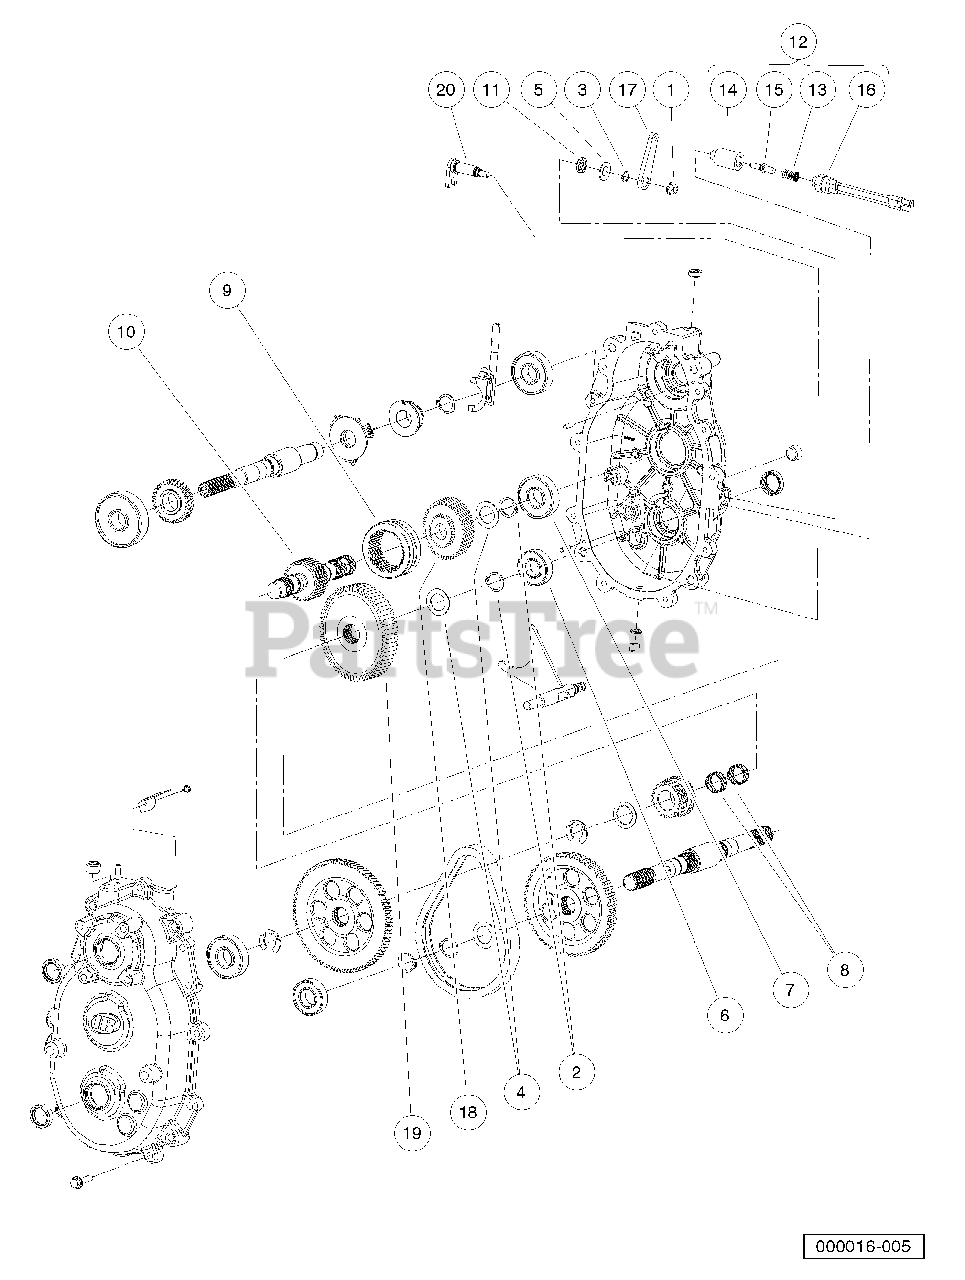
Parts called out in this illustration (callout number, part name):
1	Nut, Lock Hex, Nylon, 5/16-24
2	Ring, Retaining, Basic External
3	Ring, Retaining, External 9/16
4	Washer, Thrust, 1.007 X .062
5	Washer, Flat, .58 X 1.08 X .05
6	Bearing, Ball
7	Bearing, Ball
8	Bearing, Needle
9	Dog, Engagement
10	Shaft, Intermediate
12	Kit, Neutral Switch Repair
14	Guide, Detent Bullet
15	Bullet, Detent
16	Switch, Indicator, Pollak
17	Bellcrank, Alum
18	Gear, 35t, Spur
19	Gear, 65t, Spur
20	Shaft, Shift
